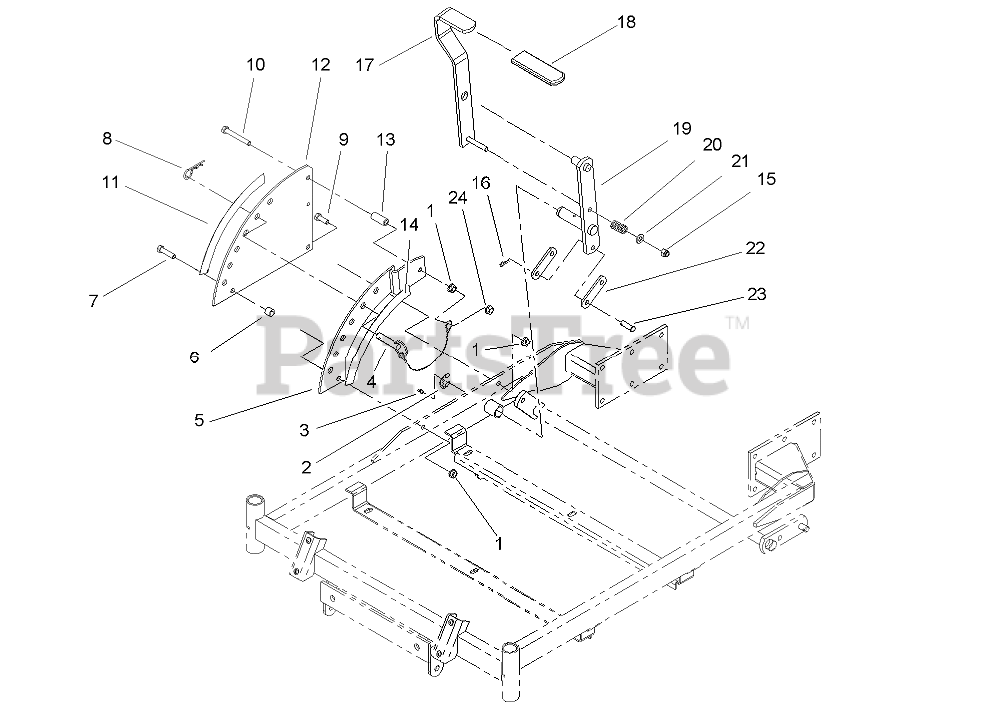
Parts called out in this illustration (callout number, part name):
1	NUT-HHF, WHIZ
2	RING-RETAINING, EXT
3	FITTING-GREASE
4	PIN-HITCH
5	PLATE-LIFT
6	BUSHING-LEVER, LIFT
7	SCREW-HH
8	PIN-COTTER
9	SCREW-HH
10	SCREW-HH
11	DECAL-DECK HEIGHT, OUTER
12	PLATE-DECK LIFT
13	BUSHING-LEVER, LIFT
14	DECAL-DECK HEIGHT, INNER
15	NUT-LOCK, NI
16	PIN-COTTER
17	LEVER-LIFT
18	GRIP-LEVER, LIFT
19	ARM-DECK, LIFT
20	SPRING-COMPRESSION
21	WASHER-FLAT
22	ARM-LIFT, DECK
23	PIN-CLEVIS
24	NUT-HF
